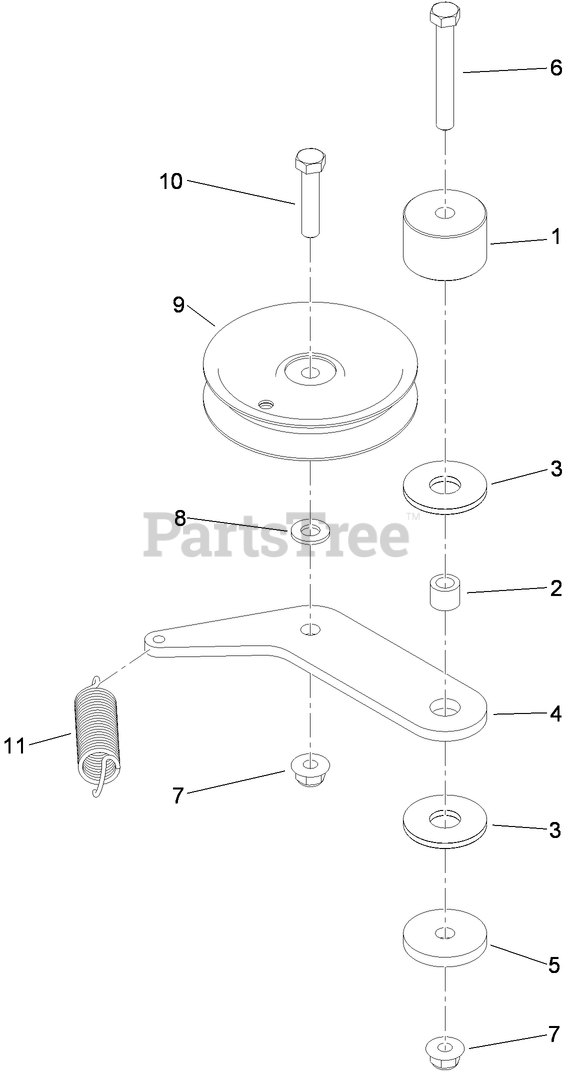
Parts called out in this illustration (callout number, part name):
1	HUB-IDLER
2	BUSHING-LEVER, LIFT
3	WASHER-FRICTION, COMPOSITE
4	PLATE-IDLER
5	WASHER-PLAIN
6	SCREW-HH
7	NUT-HF, NI
8	WASHER-FLAT
9	PULLEY-IDLER
10	SCREW-HH
11	SPRING-EXTENSION
